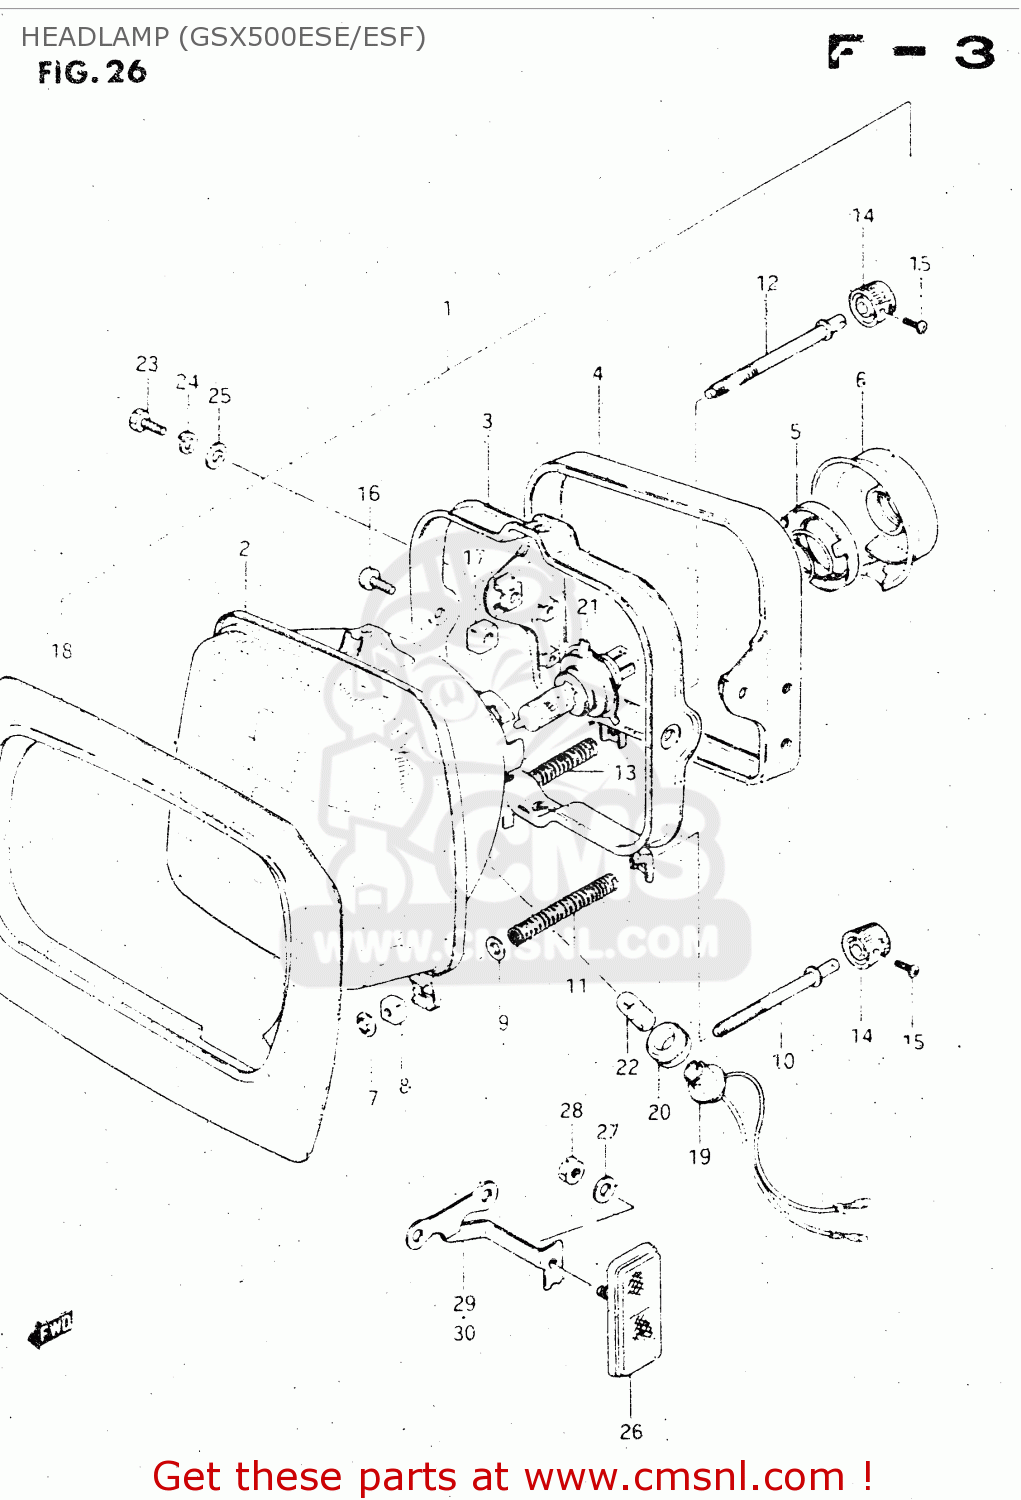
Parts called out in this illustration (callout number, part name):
1	HEADLAMP ASSY
2	LAMP UNIT
3	RING,MOUNTING
4	HOUSING,LAMP UNIT
5	HOLDER
6	COVER,HEADLAMP SOCKET
7	NUT,HEADLAMP ADJUSTER
8	NUT,HEADLAMP ADJUSTER
9	WASHER
10	SCREW,HEADLAMP ADJUST
11	SPRING
12	SCREW,ADJUSTING
13	SPRING
14	KNOB,ADJUSTER
15	SCREW
16	SCREW
17	NUT
18	SHADE
19	SOCKET
20	JOINT,RUBBER
21	BULB(12V60/55W,H4)
22	BULB(12V4W)
23	BOLT
24	WASHER,LOCK
25	WASHER
26	REFLEX REFLECTOR, FRONT SIDE
27	WASHER,5MM
28	NUT ,5MM
29	BRACKET, RH
30	BRACKET, LH
